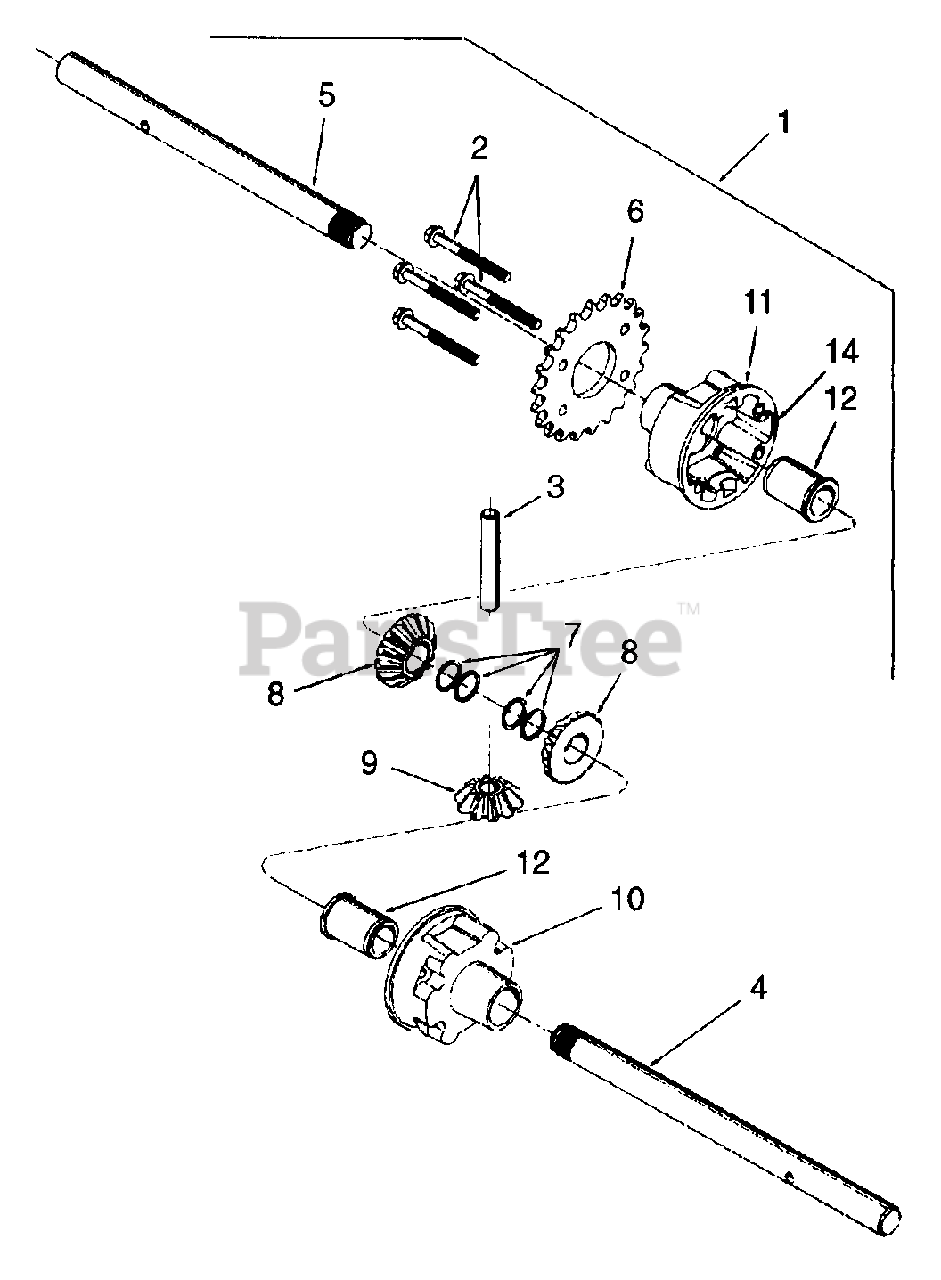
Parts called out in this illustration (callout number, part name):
1	Differential Ass'y Complete
2	Screw, Hex Wash Hd Tapp 1/4-20 x 2-5/16
3	Cross Shaft
4	Axle Shaft, .75 x 10.95
5	Axle Shaft, .75 x 9.82
6	Spocket, 22T
7	Ring, Retaining
8	Gear, Differential, 14T
9	Gear, Differential, 10T
10	Housing, Differential RH
11	Housing, Differential LH
12	Bearing, Flange, .75 ID x 1.0 OD
